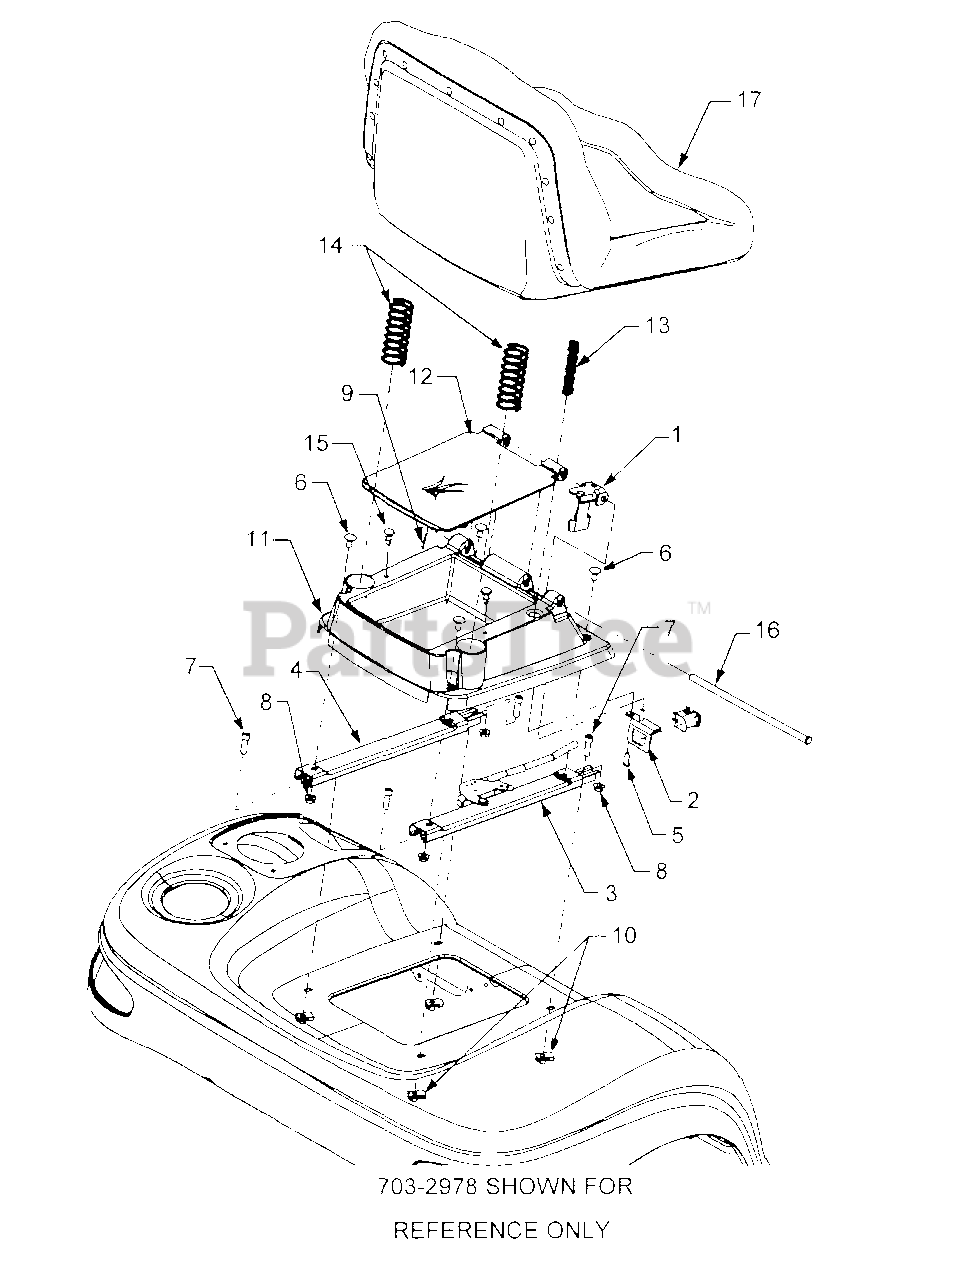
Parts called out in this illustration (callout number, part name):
1	Bracket, Seat Switch
2	Bracket, Switch Mounting
3	Track, Seat, w/Latch
4	Track, Seat, w/o Latch
5	Screw, Pan Torx Hd., #12-14 x .5
6	Carriage Bolt, 5/16-18 x .62
7	Screw, Pan Torx Hd. 5/16-18 x 1.0
8	Nut, Hex Flange Lock, 5/16-18
9	Pin, Cotter, 3/32 x .75
10	Speed Nut, U-Type, 5/16-18
11	Base, Seat
12	Lid, Tlbx
13	Spring, Compression
14	Spring, Compression
15	Bumper
16	Rod, Seat Pivot
17	Seat, High Back
